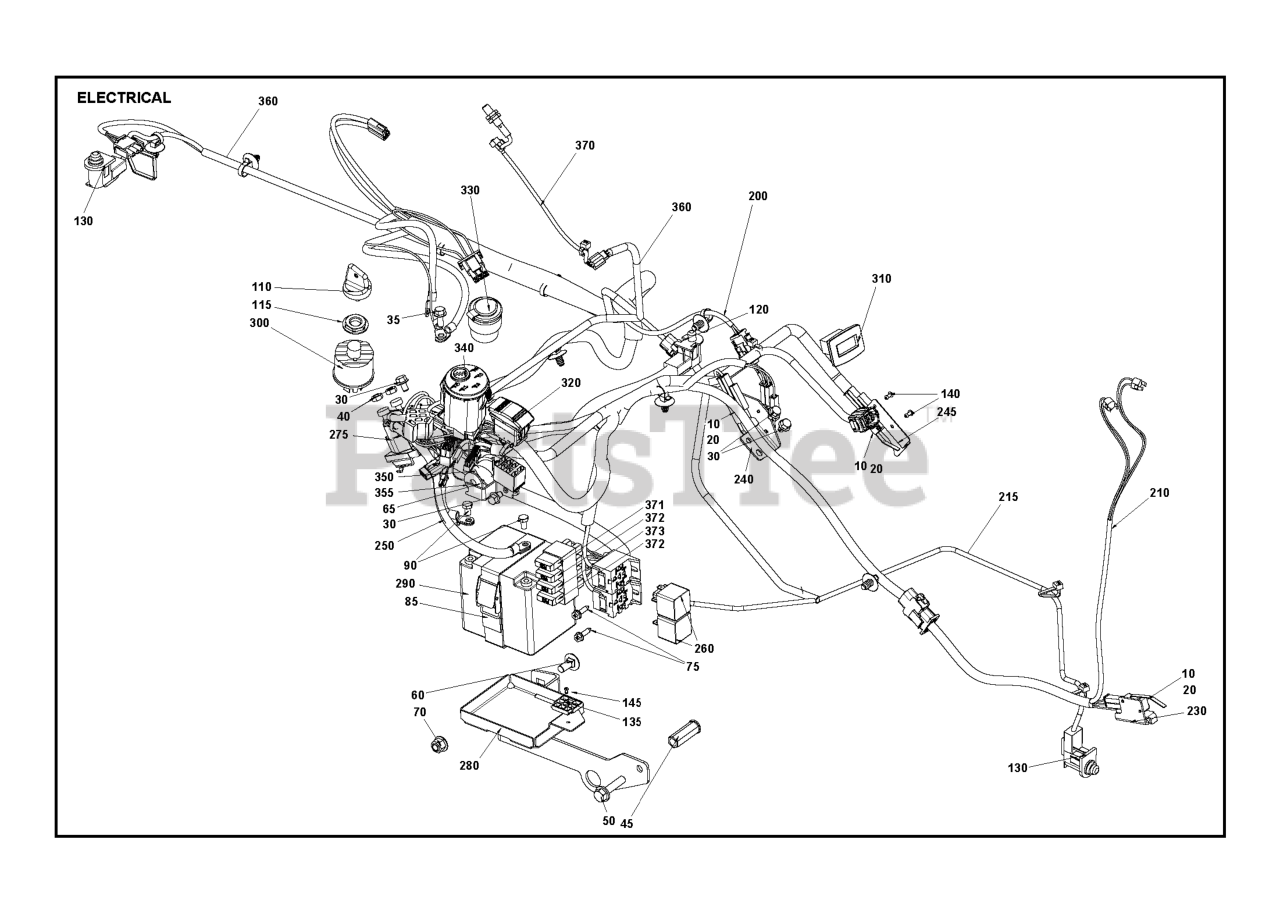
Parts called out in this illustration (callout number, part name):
10	MICRO SWITCH
35	BOLT FLANGE M6X16
50	SCREW EHHFM
70	NUT FLANGE
110	IGNITION KEY
120	SWITCH
130	REVERSE SWITCH
275	RELAY
300	IGNITION SWITCH
310	HOUR METER
